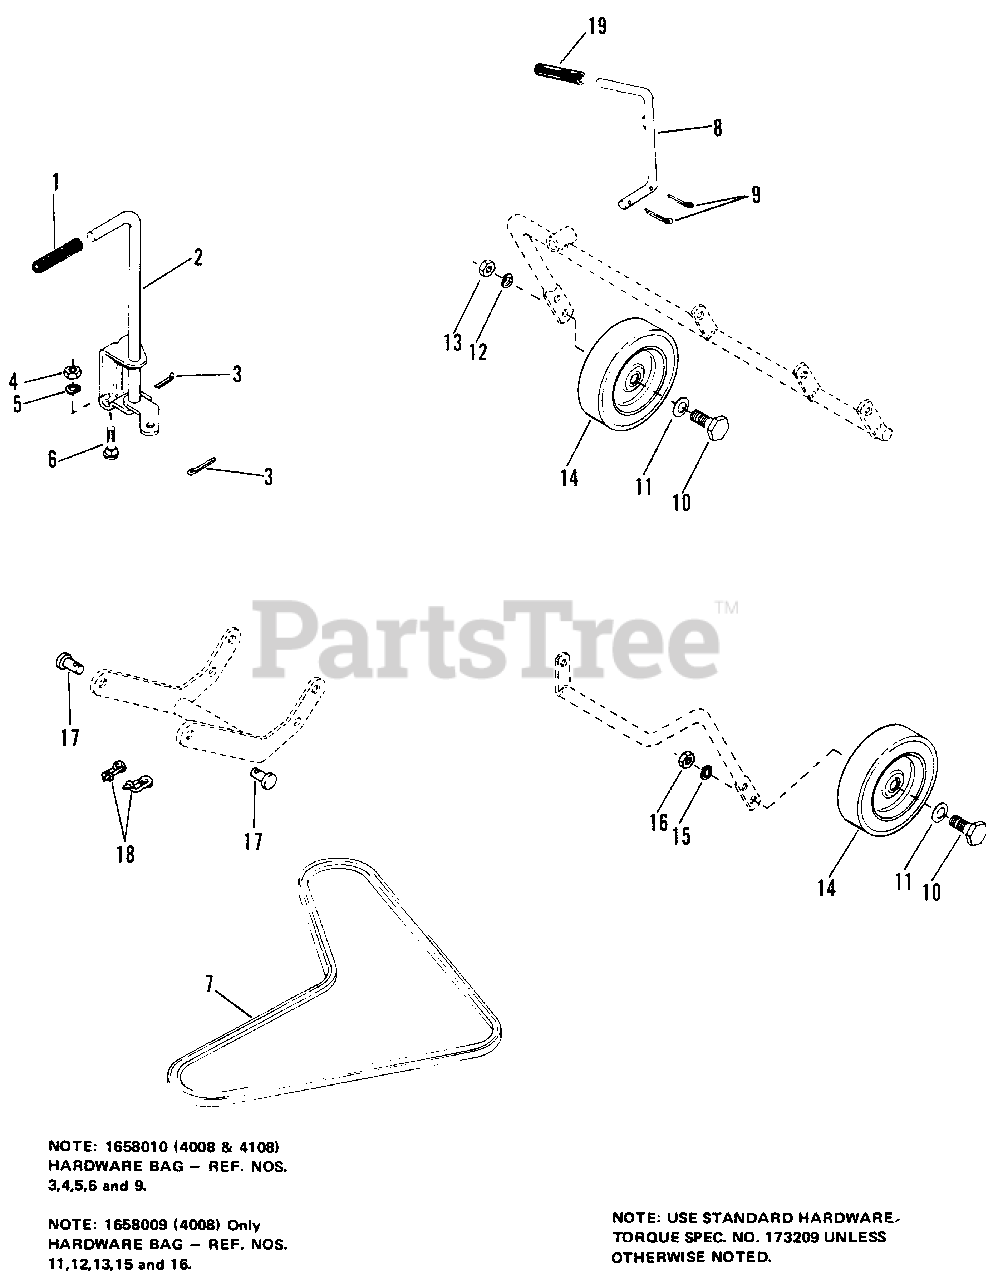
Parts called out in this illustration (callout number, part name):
1	GRIP, Handle
2	CLUTCH LEVER ASSEMBLY
3	PIN, Cotter, 3/32 x 3/4
4	NUT, Hex, 5/16-18
5	LOCKWASHER, 5/16
6	BOLT, Carriage, 5/16-18 x 3/4
7	BELT, V
8	HANDLE, Control
9	PIN, Cotter, 1/8 x 1
10	BOLT, Wheel
11	WASHER, Spring
12	WASHER, Special
13	NUT, Hex, jam, lock, 3/8-16
14	WHEEL & TIRE ASSEMBLY
15	LOCKWASHER, 3/8
16	NUT, Hex, 3/8-16
18	CLIP, Spring
19	GRIP, Handle 1/2 x 3/4
